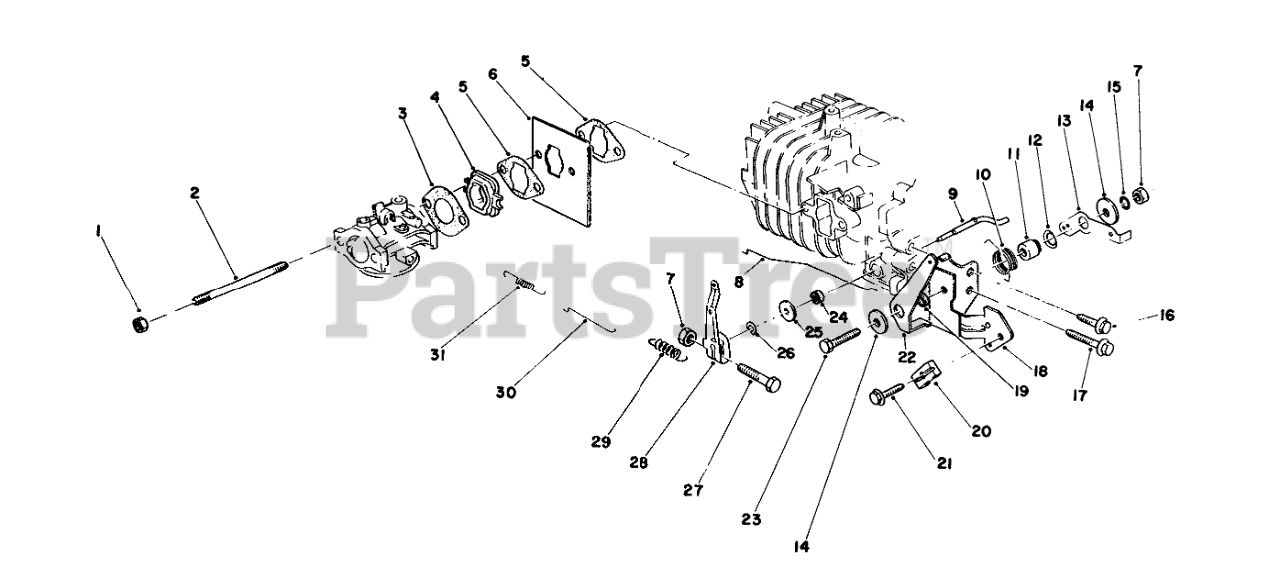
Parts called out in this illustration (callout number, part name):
1	NUT-LOCK
2	CARB STUD BOLT
3	GASKET-CARB
4	INSULATOR
5	GASKET
6	SHIELD
8	CHOKE ROD
9	Shaft-Govemor
10	Spring-Choke Control Lever
11	Gov Lever Spacer
12	Washer-Gov. Spring Lever
13	GOV SPRING LEVER
14	WASHER
15	LOCKWASHER
18	Bracket-Throttle Control
19	Spacer-Choke Control Lever
20	CLAMP-CABLE
22	LEVER-CONTROL, CHOKE
24	SEAL-OIL
25	WASHER
26	E-RING
27	Bolt-Throttle Lever
28	Lever-Throttle Control
29	GOVERNOR SPRING
30	ROD-CARBURETOR
31	SPRING
